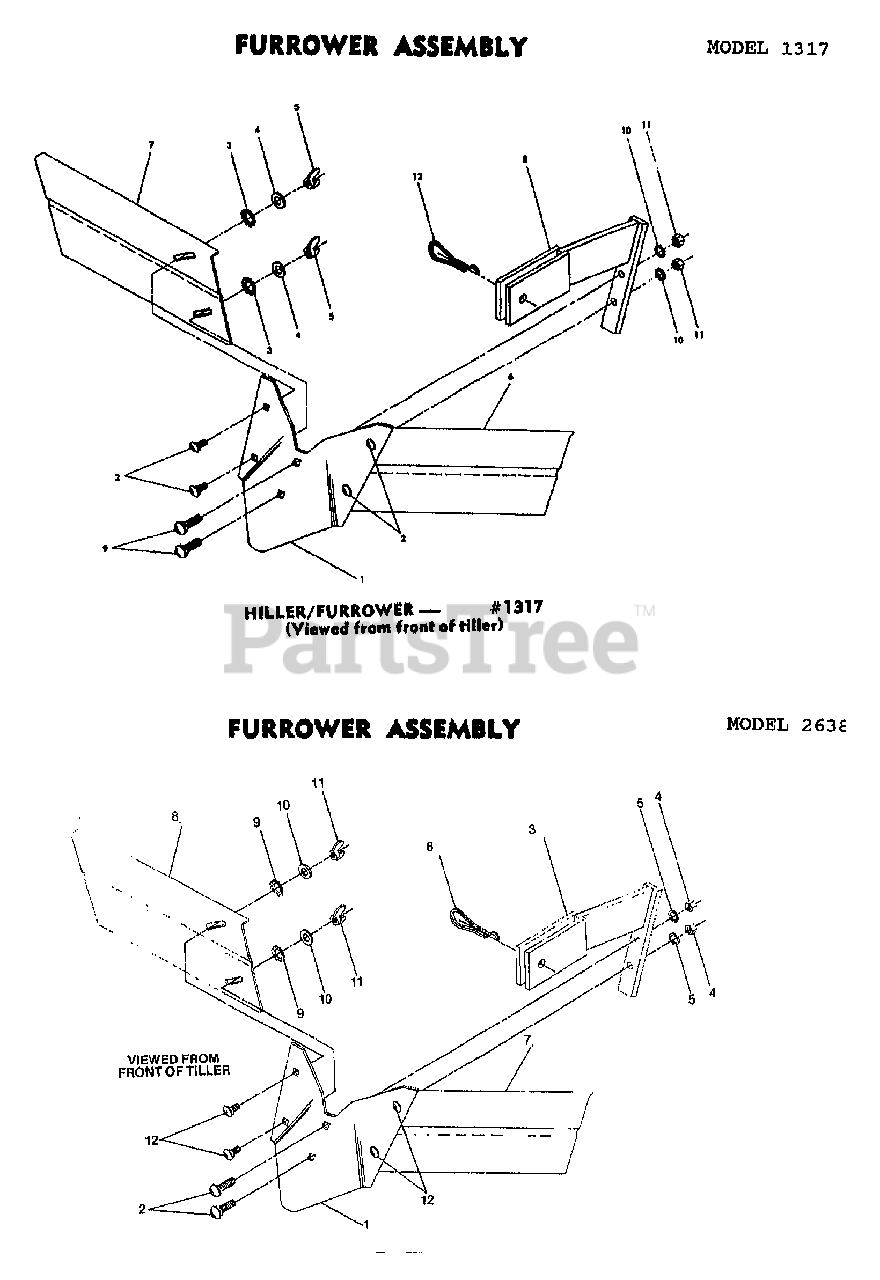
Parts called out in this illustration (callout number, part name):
1	BLADE-FURROWER PNT
2	SCR-CARR 5/16-18X.75 G2 ZP
3	WASHER-LK .312 EXT TOOTH
4	WASHER-FLAT 5/16 SAE
5	NUT-WING/LK 5/16-18 ZP
6	WING-HILLER LEFT PNT
7	WING-HILLER RIGHT PNT
8	BRKT-H/F PNT
9	BOLT-CARR 3/8-16X1.5 ZP
10	WASHER-LK .375 @ DEPL
11	NUT-HEX 3/8-16 ZP
12	PIN-CLINCH .312DIA ZP
